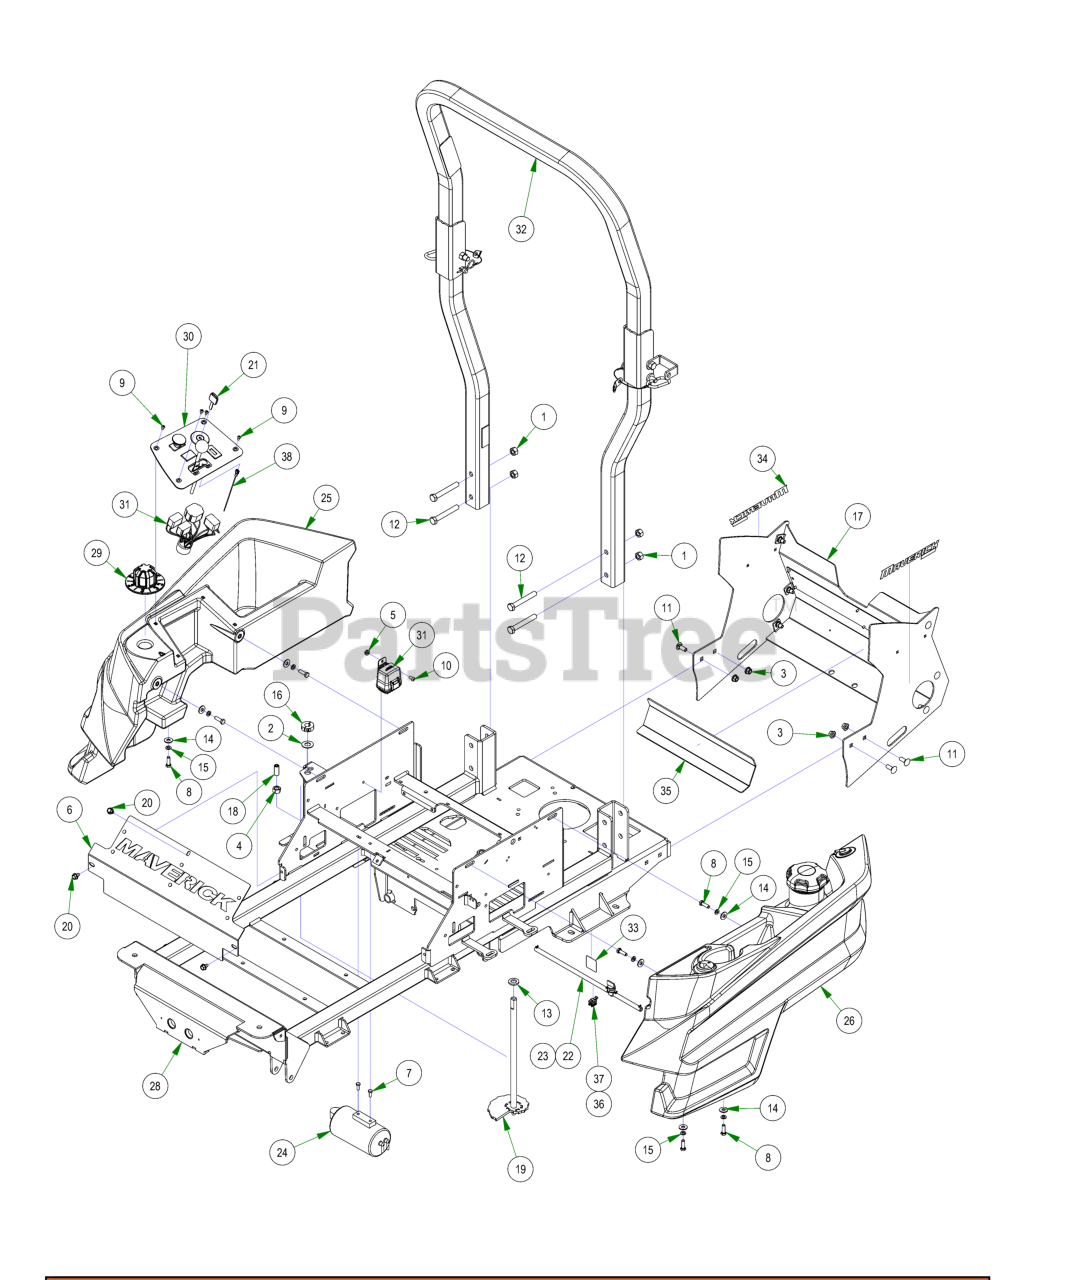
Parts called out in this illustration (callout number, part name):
1	1/2-13 HEX 2-WAY REVERSIBLE CENTER LOCKNUT Grade B ZINC
2	.625 ID x 1.250 OD x .062 THK F/W Nylon
3	3/8-16 NYLON INSERT FLANGE LOCKNUT (GR.F) ZINC
4	1/2-13 HEX NUT ZINC
5	1/4-20 HEX SERRATED FLANGE NUT HARD/ZINC
6	2021 Maverick Cooler Cover Assembly
7	M6-1.0 X 16MM DIN 933 HEX TAP BOLT (CL 8.8) ZINC
8	5/16-18 X 1 HEX CAP SCREW (GR.5) ZINC
9	10-32 X 3/8 BUTTON SOCKET CAP SCREW 18-8 STAINLESS
10	1/4-20 X 1/2 BUTTON SOCKET CAP SCREW 18-8 STAINLESS
11	3/8-16 X 1 CARRIAGE BOLT (GR.5) ZINC
12	1/2-13 X 3-1/2 HEX CAP SCREW (GR.5) ZINC
13	.635 ID X 1.120 OD X .140 THICK FLAT WASHER NYLON
14	5/16 USS FLAT WASHER (7/8 OD) ZINC
15	5/16 SPLIT LOCKWASHER ZINC
16	5/8" Split Collar
17	2022 Maverick Rear Cover Assembly
18	Dial Rod Plunger
19	ZT Deck Height Bar Assembly
20	5/16-18 X 1/2 HWH unslot (F) tcs zinc
21	Ignition Key
22	15" Fuel Line Assembly
23	37" Fuel Line Assembly
24	ZT/Mav EPA Cannister Assy
25	2021 Maverick Right Side Tank
26	2021 Maverick Left Side Tank
27	Fuel Pick-up for 067-2021-00
28	2023 Maverick Frame - Painted
29	MZ/ZT Deck Height Dial
30	2023 Control Panel Assembly
31	2024 Wiring Harness with Clips
32	2016 2x2 ROPS
33	Patent Decal
34	Maverick Back Plate Decal
35	Heat Shield (Fiberglass Adhesive)
36	Edge Clip With Ziptie
37	Edge Clip With Ziptie
38	2017 MZ/ZT/MAV Tach Wire Assy
